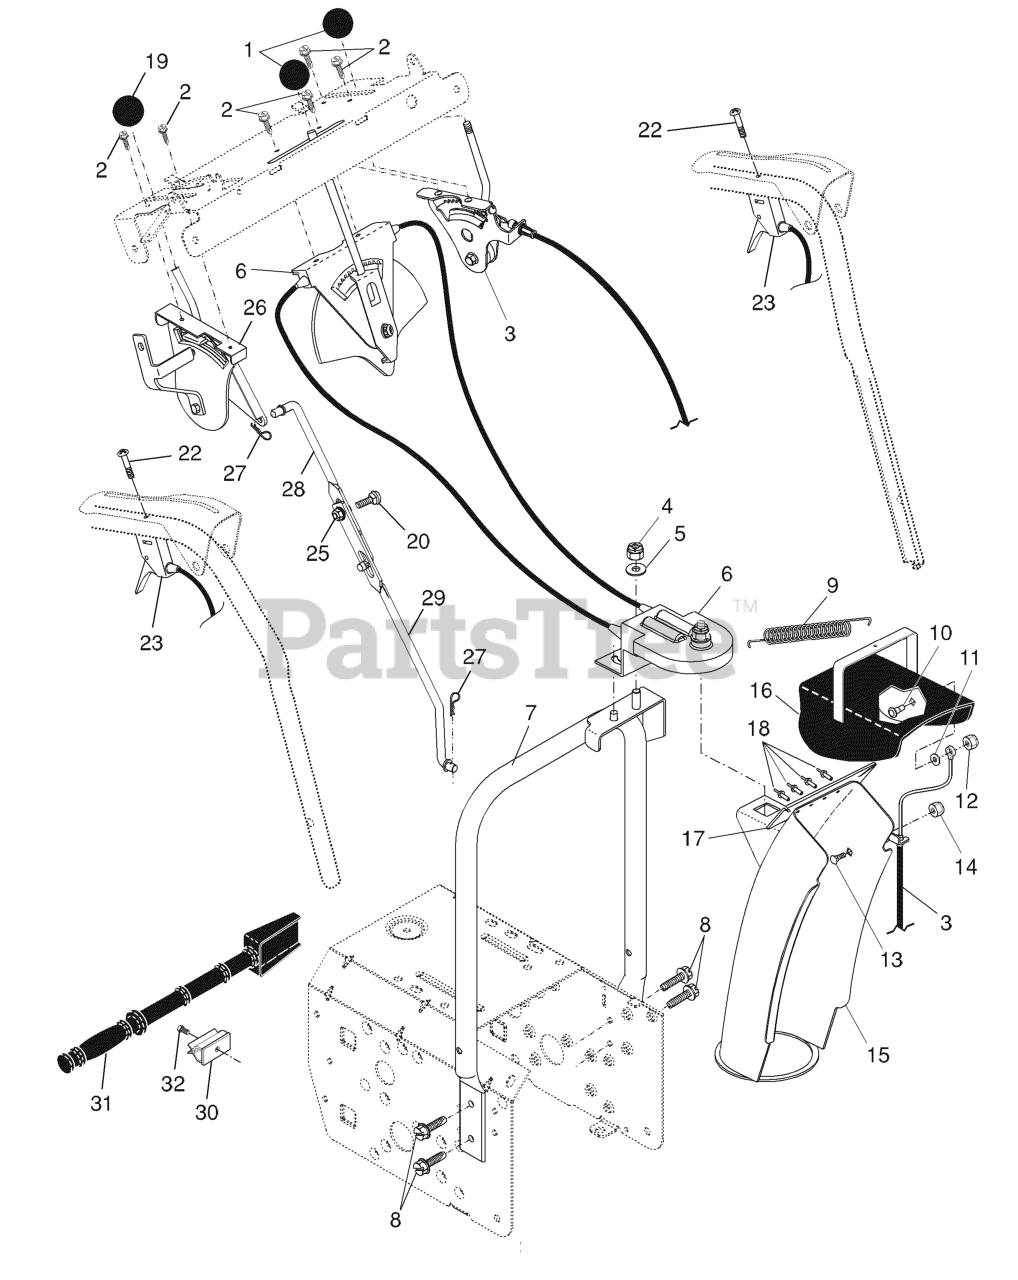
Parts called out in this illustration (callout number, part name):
1	KNOB LEVER, BLACK
2	SCREW #10-24 X 5/8
3	CONTROL.CABLE.DEFLECTOR
4	NUT
5	WASHER
6	CONTROL ASSEMBLY,CHUTE ROTATER
7	SUPPORT, PIVOT
8	SELF-TAPPING SCREW 5/16-18X3/4
9	SPRING.DEFLECTOR.REM.CHUTE
10	BOLT, SHOULDER
11	WASHER, NYLON FRICTION
12	NUT.HEX.FLANGE.1/4
13	BOLT
14	NUT.LOCK.5/16-18
15	CHUTE ASSEMBLY
16	DEFLECTOR.WELDMENT.PNT.ORANGE
17	SEAL, DEFLECTOR
18	RIVET BLIND
19	RED KNOB SHIFTER
20	BOLT
23	STEERING.CONTROL.SNOW.BLUE
25	NUT.FLANGE.5/16
26	HEAD ASSY SPEED
27	SPRING RETAINER
28	ROD, UPPER SPEED CONTROL
29	ROD, LOWER SPEED CONTROL.SNOW
30	CLIP.CLEANOUT.TOOL
31	CLEAN OUT TOOL
32	SCREW.HWH.13-16-5.8.BZP
